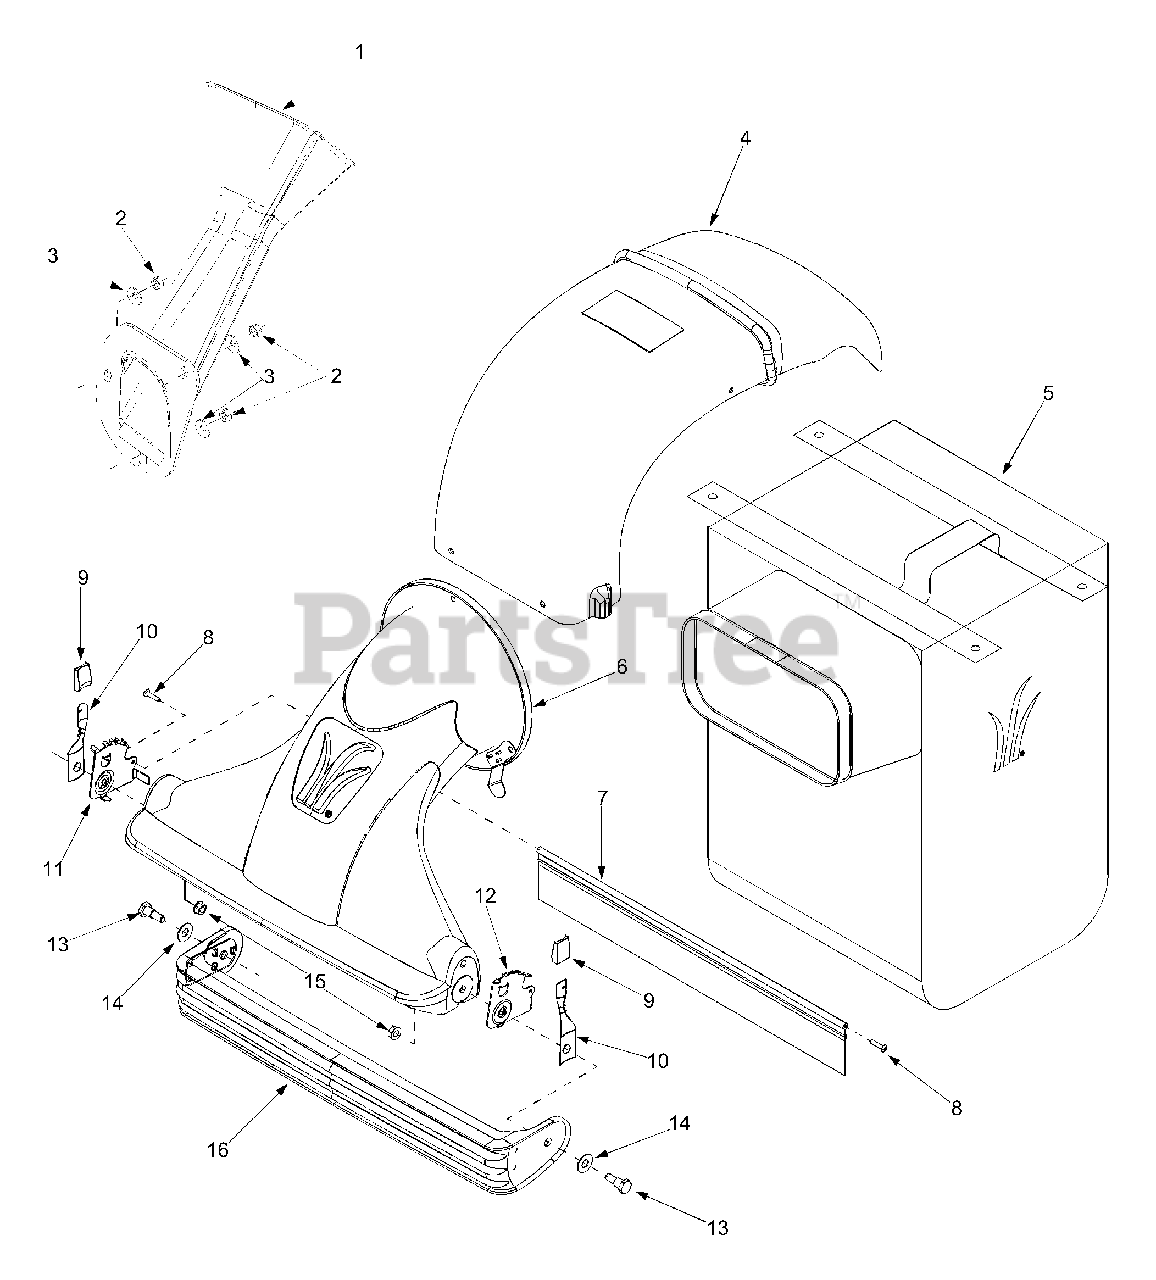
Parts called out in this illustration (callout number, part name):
2	Hex Nut 5/16-18
3	Bell Washer .340 ID x .872 OD
4	Discharge Chute
5	Bag
6	Nozzle Assembly
7	Nozzle Flap
8	Screw
9	Height Adjustment Knob
10	Spring Lever
13	Shoulder Screw
14	Flat Washer .510 x 1.120 x .060
15	Hex Flange Lock Nut 3/8-16
16	Door Assembly
